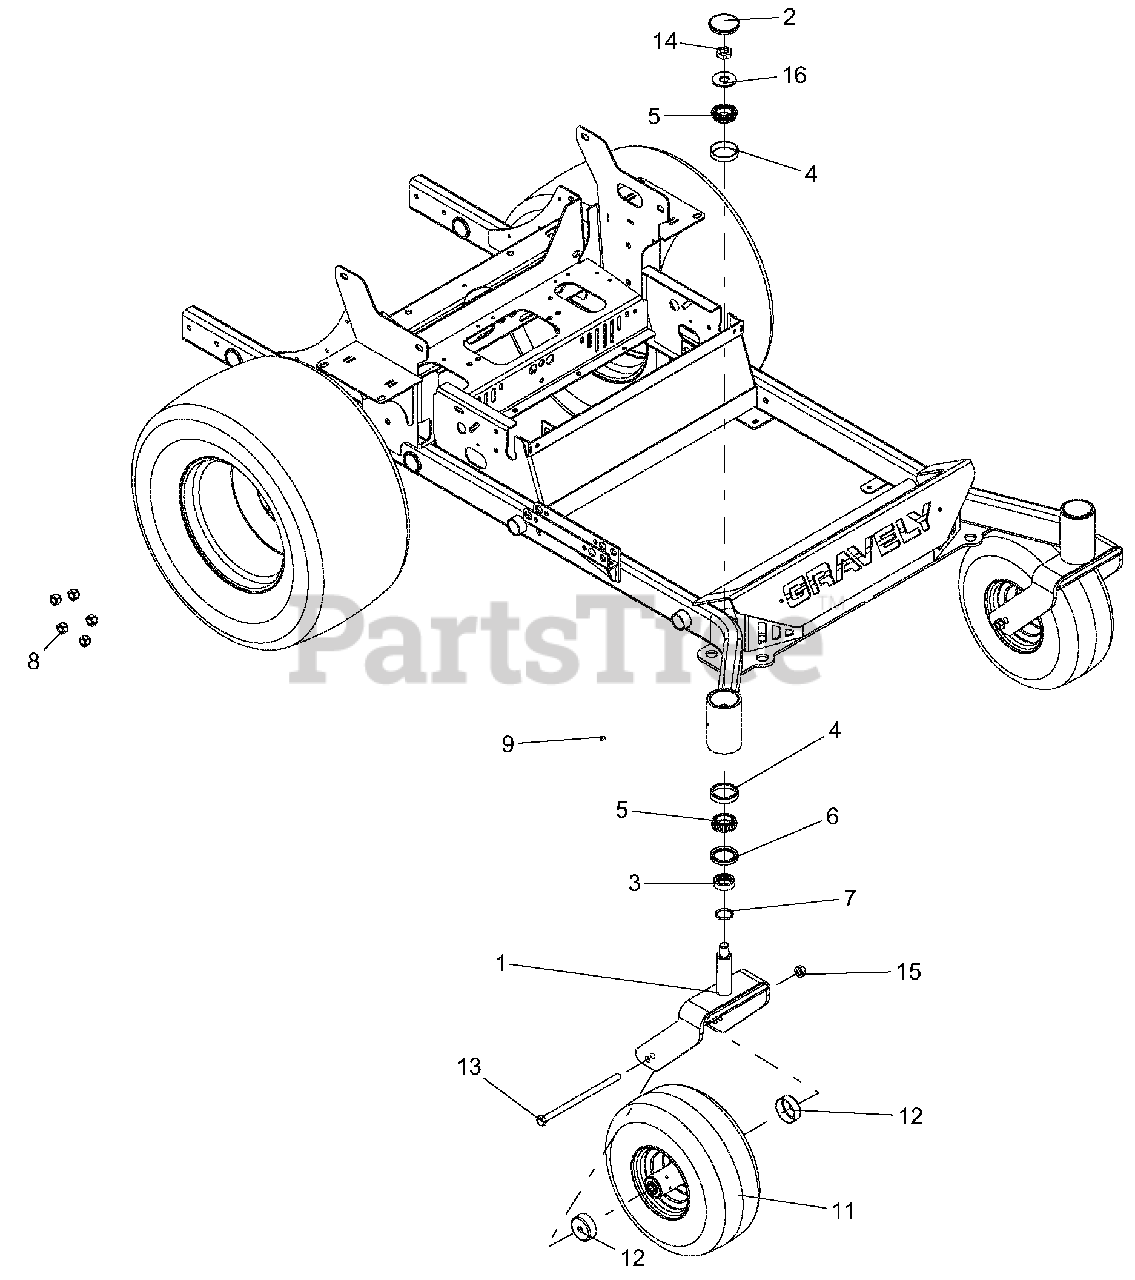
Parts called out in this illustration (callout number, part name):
1	WMT, CASTER FORK - RED
2	CAP, DUST
3	SPCR, FRONT CASTER FORK
4	BRG, CUP 2.328 X .465
5	BRG, CONE 1.250 X .660
6	SEAL, OIL 1.75 X 2.332 X .312
7	O-RING, .139 W X 1.234 ID
8	NUT, LUG .500-13
9	FITTING, .250-28 FLUSH MOUNT GREASE
11	TIRE/WHEEL, 15 X 6.00-6 SEMI-PNEU
12	SHIELD, WHEEL BEARING
13	BLT-HEX .50-13X9.00 GR5 YWZC
14	@NUT-LK-CTR-JAM .75-16 YWZC
15	NUT, LK-TOP-FLG .50-13 YWZC
16	WSHR-FL-STL.812X2.00X.148YWZC
